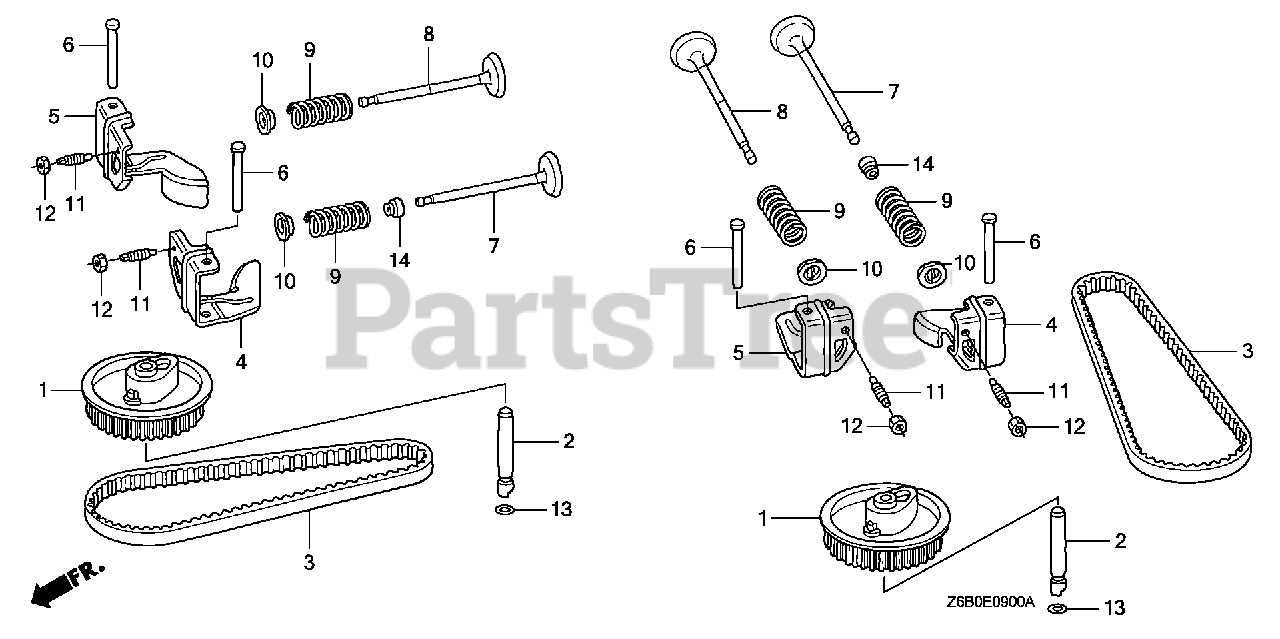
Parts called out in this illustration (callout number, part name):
1	PULLEY, CAMSHAFT
2	SHAFT, CAM PULLEY
3	BELT, TIMING (97HU8 G-200)
4	ARM, IN. VALVE ROCKER
5	ARM, EX. VALVE ROCKER
6	SHAFT, ROCKER ARM
7	VALVE, IN.
8	VALVE, EX.
9	SPRING, VALVE
10	RETAINER, IN. VALVE SPRING
10	RETAINER, VALVE SPRING (EXHAUST SIDE)
11	SCREW, TAPPET ADJ.
12	NUT, TAPPET ADJ.
13	O-RING (6.8X1.9) (ARAI)
14	SEAL, VALVE STEM
